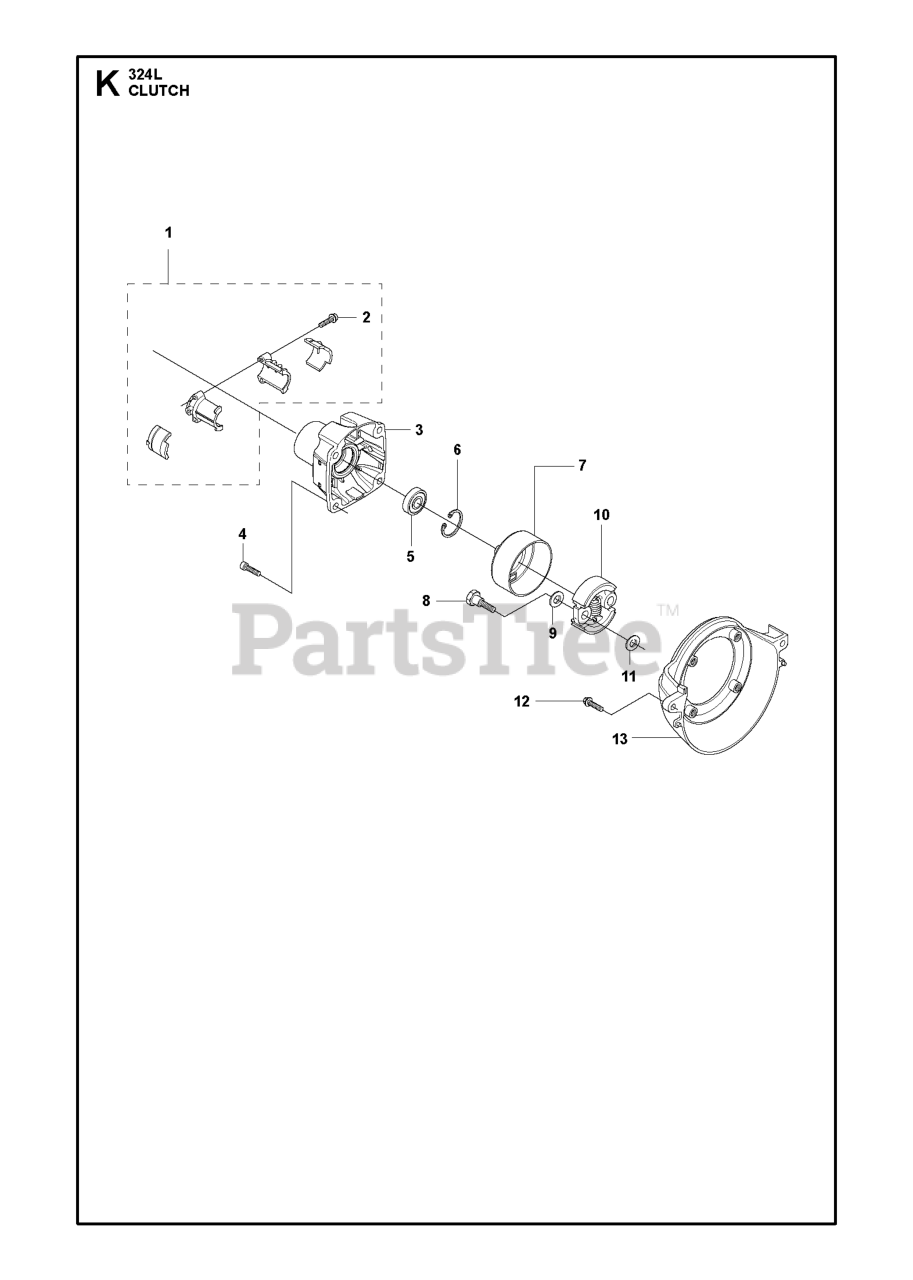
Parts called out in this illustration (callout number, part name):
1	COMPRESION SLEEVE/ISOLATOR SET
3	CLUTCH HOUSING
4	SCREW MC6S 6X20
6	RETAINING RING
7	CLUTCH DRUM ASSY
